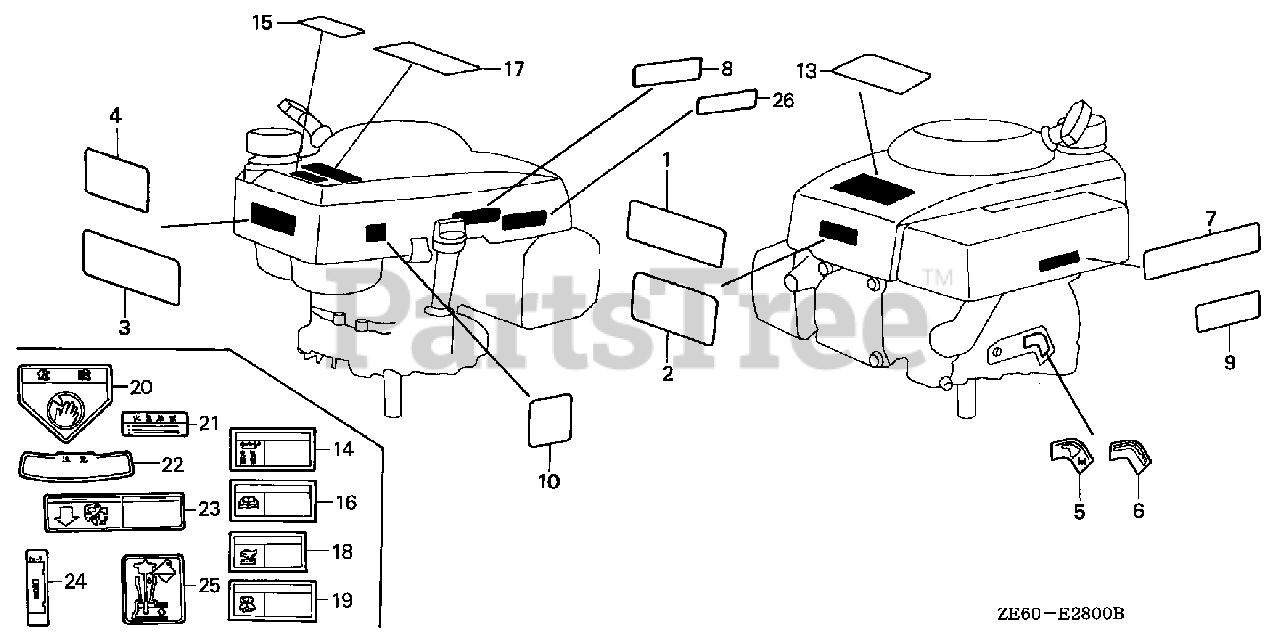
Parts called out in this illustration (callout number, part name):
2	MARK, TOP COVER
3	MARK, CAUTION (USA)
6	MARK, CONTROL
7	MARK, AIR CLEANER CAUTION
10	MARK, OIL CAUTION
